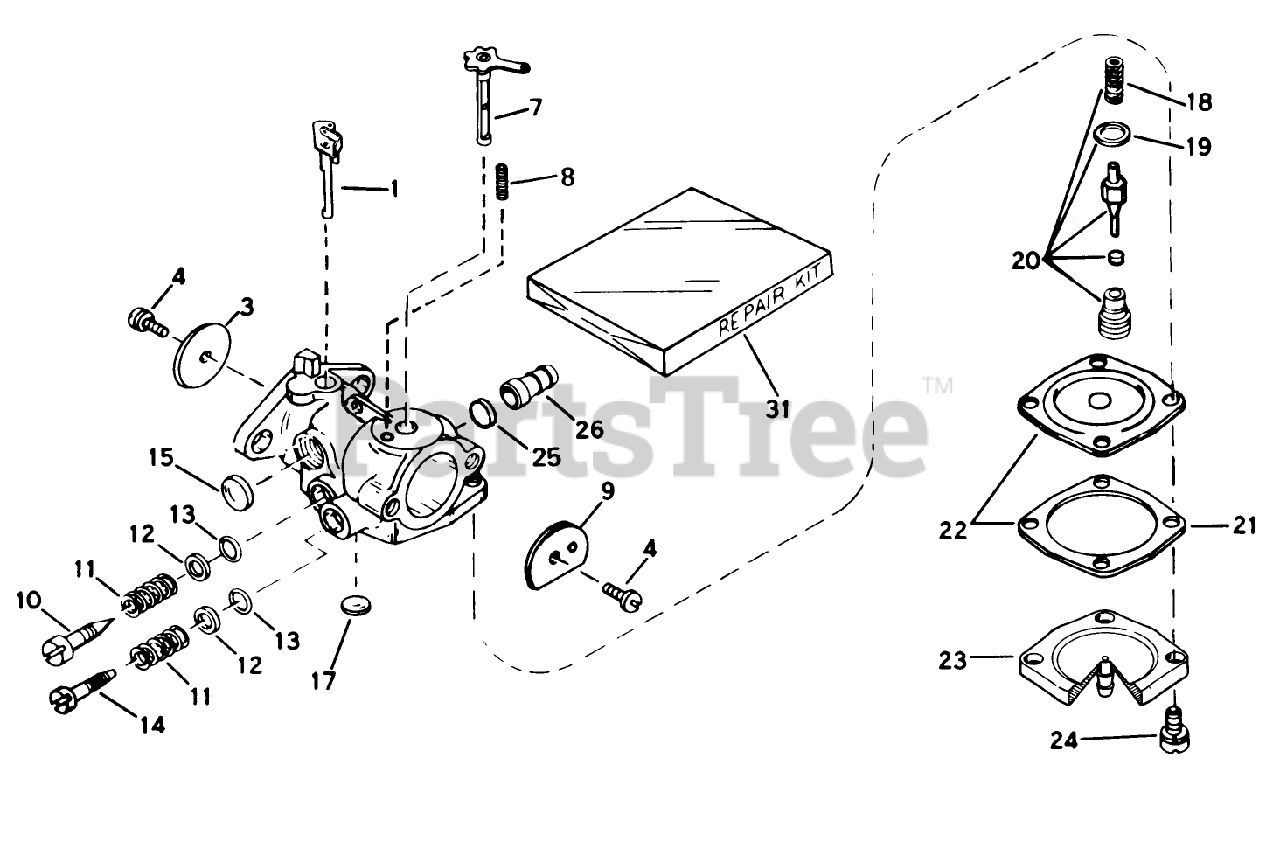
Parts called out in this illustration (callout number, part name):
1	Shaft/Lever-Throttle
3	Shutter-Throttle
4	Screw-Shutter
7	Shaft Lever Assembly
8	Spring-Positioning, Choke
10	Screw-Idle Adjustment
11	Spring
12	Washer
13	ORing
14	Screw Main Adjustment
15	Plug-Welch, Idle Mixture Well
17	Plug, Welch
18	Spring-Valve
19	Gasket-Valve Seat
20	Inlet Needle, Seat, Spring Gasket Assy. (lncl. #1819)
21	Gasket-Diaphragm
22	Diaphragm Ass. (Incl. No. 21)
23	Cover, Diaphragm
24	Screw
25	Valve Check
26	Fuel Fitting
31	Kit-Repair
